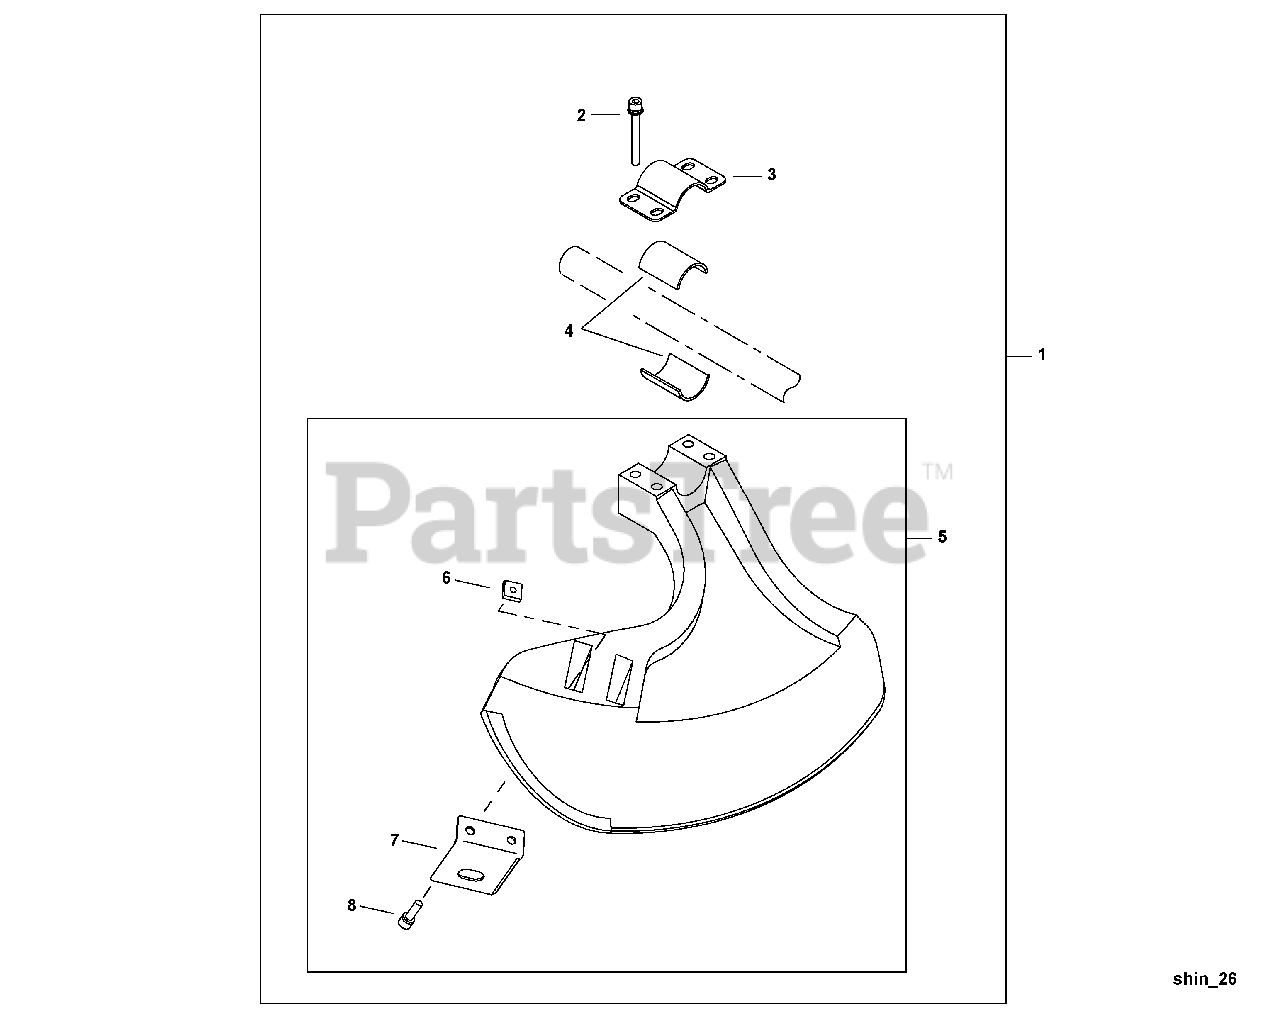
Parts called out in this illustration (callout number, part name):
1	DEBRIS SHIELD KIT
2	BOLT M5×45
3	CLAMP, UPPER
4	SPACER 26
5	DEBRIS SHIELD ASSY
6	NUT M5
7	CUTTER
8	BOLT M5×16
